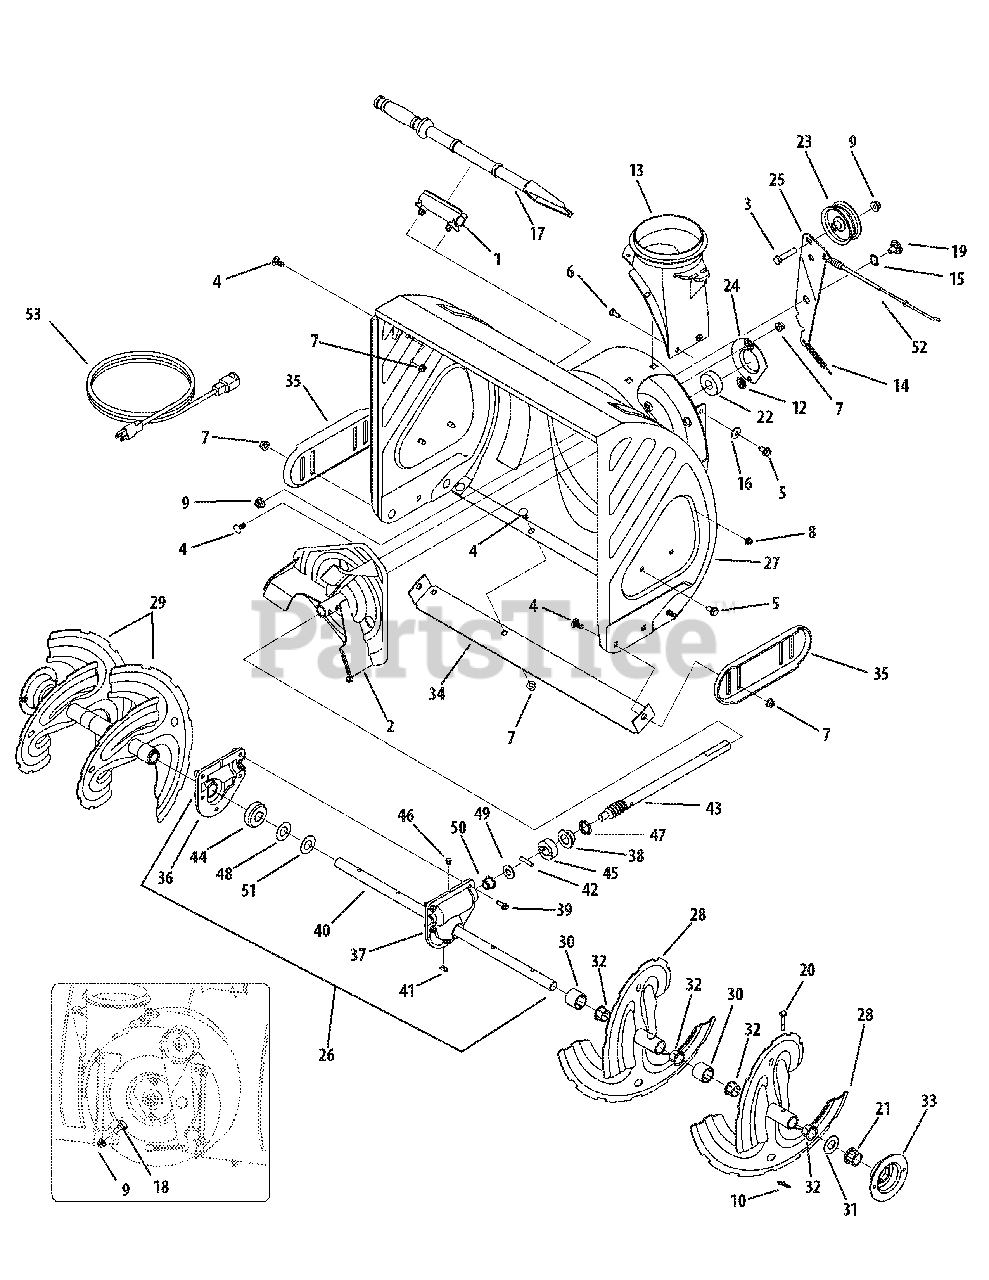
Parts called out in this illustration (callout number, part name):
1	Clean-out Tool Bracket
2	Impeller Assembly, 12" Dia.
3	Hex Screw, 3/8-16, 1.75, Gr5
4	Carriage Bolt, 5/16-18, .750 Gr1
5	Screw, 5/16-18, 0.625
6	Carriage Screw, 1/4-20, .750, Gr5
7	Flange Lock Nut, 5/16-18, Nylon
8	Flange Lock Nut, 1/4-20, Nylon
9	Flange Lock Nut, 3/8-16, Nylon
10	Bow-tie Cotter Pin
11	Cable Tie, 3/16 x .05 x 7.4
12	Speed Nut
13	Chute Adapter
14	Extension Spring, .38 OD x 3.6
15	Wave Washer, .625 x .885 x .015
16	Bell Washer, .340 x .872 x .060
17	Clean-out Tool
18	Shoulder Screw, .498 x .34, 3/8-16
19	Shoulder Screw, .625 x .17, 3/8-16
20	Shear Pin, .25 x 1.50
21	Hex Flange Bearing x .75 ID
22	Ball Bearing, .75 ID x 1.85 OD
23	Idler Pulley, 2.75 OD
24	Bearing Housing, 1.85 ID
25	Auger Idler Bracket w/ Brake
26	Auger Gearbox Assembly, 30"
27	Auger Housing Assembly, 30"
28	Spiral Assembly, LH
29	Spiral Assembly, RH
30	Spacer, 1.25 OD x .75 ID x 1.00
31	Flat Washer, .76 x 1.49 x .06
32	Flange Bushing, .80 ID x .91 OD
33	1" Hex Bearing Housing
34	Shave Plate, 30"
35	Skid Shoe, Deluxe
36	Auger Housing, RH Reduced
37	Auger Housing, LH Reduced
38	Flange Bearing, .75 x 1.0 x .59
39	Self-tapping Screw, 1/4-20, 0.750
40	Auger Axle, 30"
41	Hi-pro Key, 3/16 x 5/8
42	Dowel Pin, .25 OD x 1.2
43	Worm Shaft, .75 OD
44	Worm Gear, 20T
45	Thrust Collar
46	Plug, 1/4 x .437
47	Oil Seal, .75 x 1 x .131
48	Flat Washer, .760 ID x 1.5 OD
49	Flat Washer, .51 x 1.12
50	Flange Bearing, .75 x 1.0 x .925
51	Spacer, 1.25 x .75 x 3/16
52	Auger Clutch Cable, 47.23"
53	Extension Cord, 110V, 3-Prong
